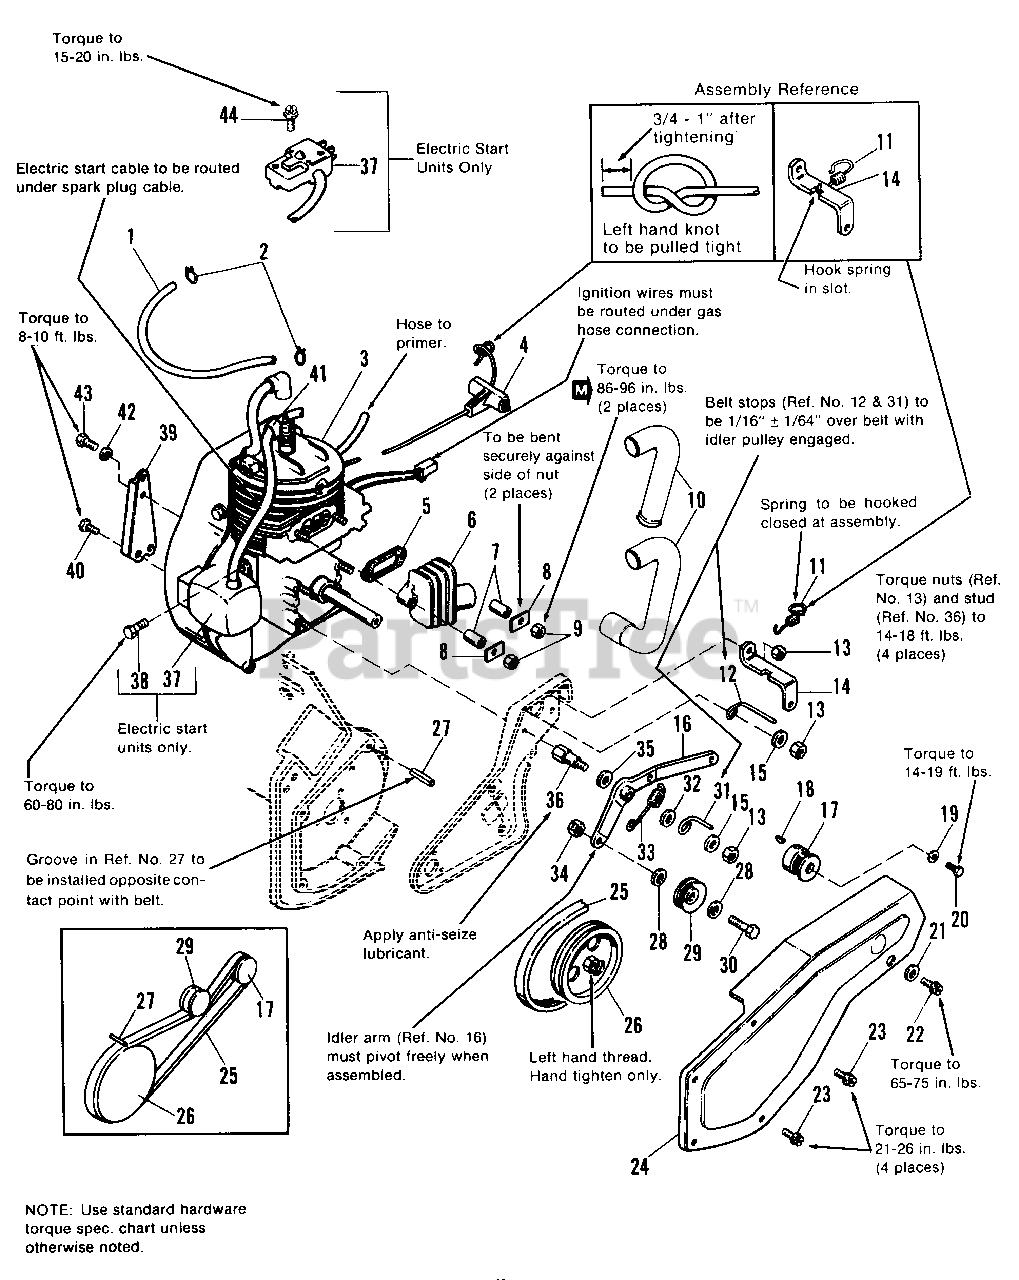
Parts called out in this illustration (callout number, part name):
2	CLAMP, Hose
3	ENGINE
4	HANDLE, Pull
5	GASKET, Exhaust Manifold
6	MANIFOLD, Exhaust
8	KEEPER, Nut
9	LOCKNUT, Hex, 1/4-20
10	PIPE, Exhaust (1690354 before s/n 29431)
10	PIPE, Exhaust (1690354 after s/n 29430)
10	PIPE, Exhaust (1690357 before s/n 12743)
10	PIPE, Exhaust (1690357 after s/n 12742)
11	SPRING, Extension
12	STOP, Belt
13	LOCKNUT, Center, Full, 5/16-18
14	BRACKET, Cover
15	WASHER, Plain, 5/16
16	ARM ASSY., Idler
17	PULLEY, Drive
18	KEY, Woodruff, 5/32 x 5/8
19	LOCKWASHER, 5/16
20	CAPSCREW, Hex Hd., 5/16-24 x 3/4
21	WASHER, Belleville
22	SCREW, Wash. Hd., Hex, Slotted, #10-14 x 5/8
23	SCREW, Wash. Hd., Hex, Slotted, #10-14 x 1/2
24	COVER, Belt
25	BELT, Drive
26	PULLEY, Driven
27	GUIDE, Belt
28	WASHER, Plain, 3/8
29	PULLEY, Idler
30	CAPSCREW, Hex Hd., 3/8-16 x 1-1/4
31	STOP, Belt
32	WASHER, Plain, 5/16
33	SPRING, Tension
34	LOCKNUT, Hex, Center, 3/8-16
37	KIT, Electric Start
38	CAPSCREW, Hex Hd., 1/4-20 x 1/2 (Used on E.S. only)
39	BRACKET, Engine
40	SCREW, Hex, Taptite, 1/4-20 x 1/2
41	CLIP, Tinnerman (Used on E.S. only)
42	LOCKWASHER, 1/4
43	CAPSCREW, Hex hd., 1/4-20 x 3/8
44	SCREW, Round Hd., #8 x 3/4 (Used on E.S. only)
